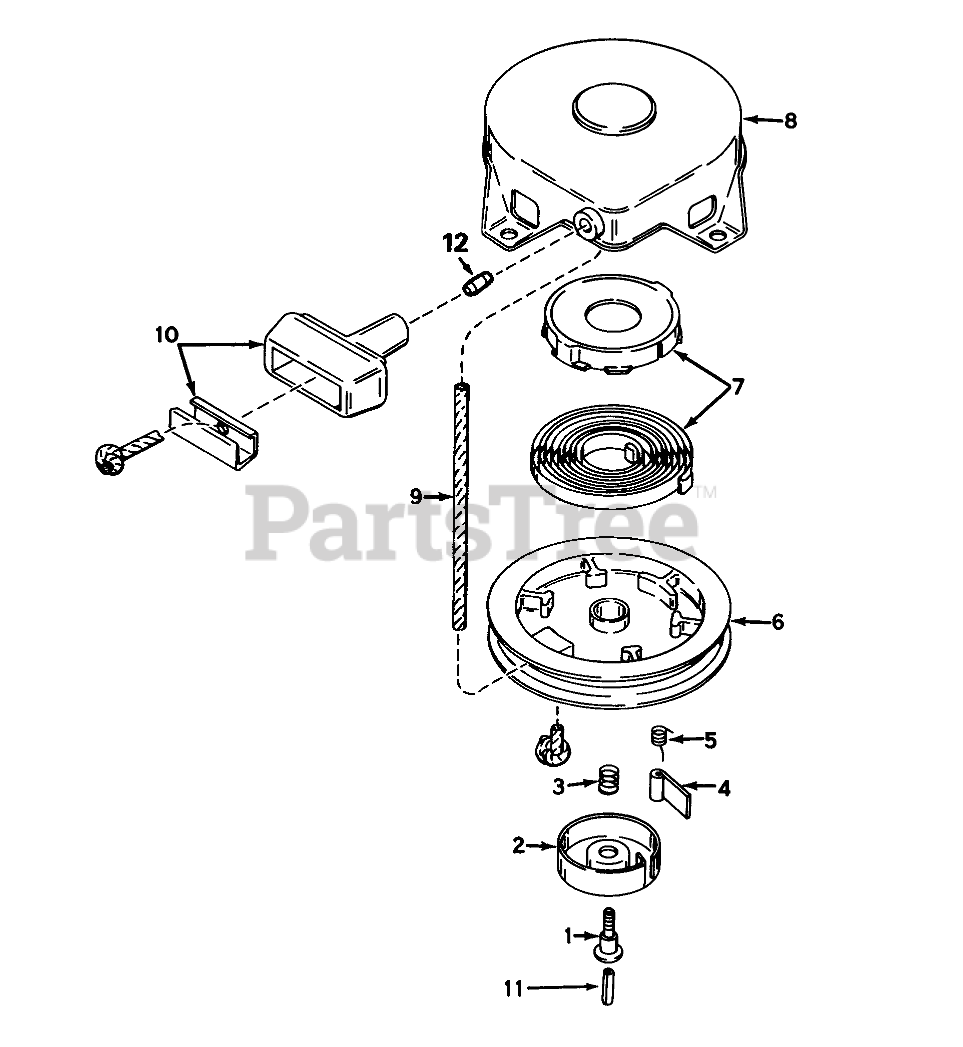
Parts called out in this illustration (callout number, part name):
1	Screw
2	Retainer
3	Spring-Brake
4	Dog-Starter
5	Spring-Dog
6	Pulley
7	Spring & Keeper Assy
8	Housing Assy., Starter (Incl. Ref. #1)
9	Rope-Starter (98 cut to length)
10	Assy., Starter
11	Centering
12	Retainer-Starter Rope
